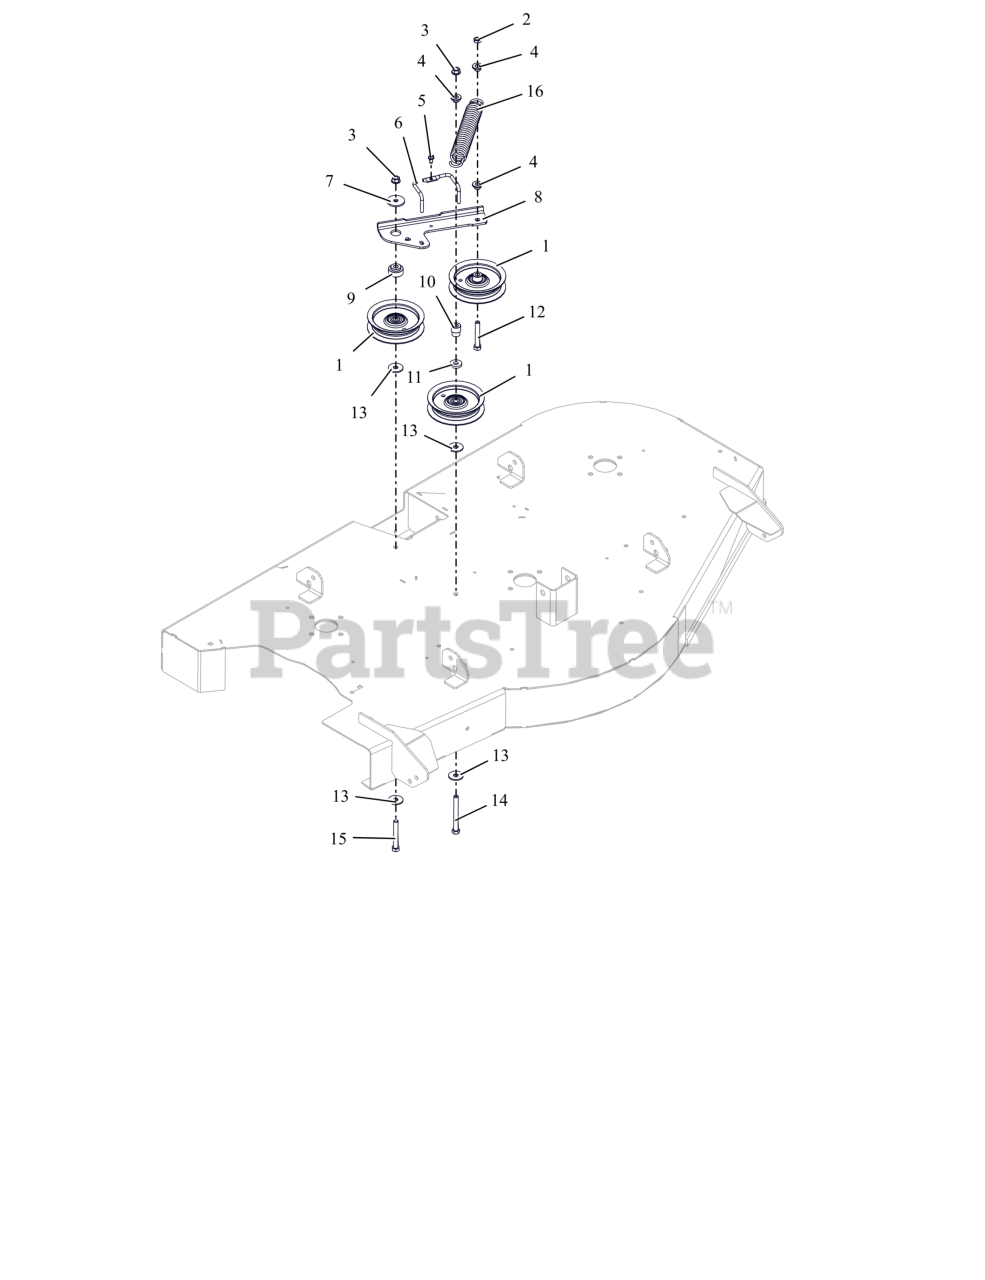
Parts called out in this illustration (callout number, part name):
1	IDLER, FLAT - 4.06" X .75"
2	NUT-LK-CTR-JAM .375-16 GB ZCC
3	NUT-LK-CTR-FLG .375-16 GF ZCC
4	BSHG-FLG .385X.500X.875X.406
5	SCR-TAP .25-20X.50 HWH ZCC
6	WIREFORM, BELT FINGER
7	WSHR, FLT .380X1.50X.125 ZCC
8	ARM- IDLER EDGE
9	BSHG- FLANGED
10	BUSHING, IDLER (P/M)
11	WSHR, FLT .406X1.00X.188 ZCC
12	BLT, HEX .38-16X2.50 G5 ZCC
13	WSHR FL STL .406X1.25X.10ZC120
14	BLT, HEX .38-16X3.50 G5 ZCC
15	BLT, HEX .38-16X2.75 G5 ZCC
16	SPRG, EXTENSION
